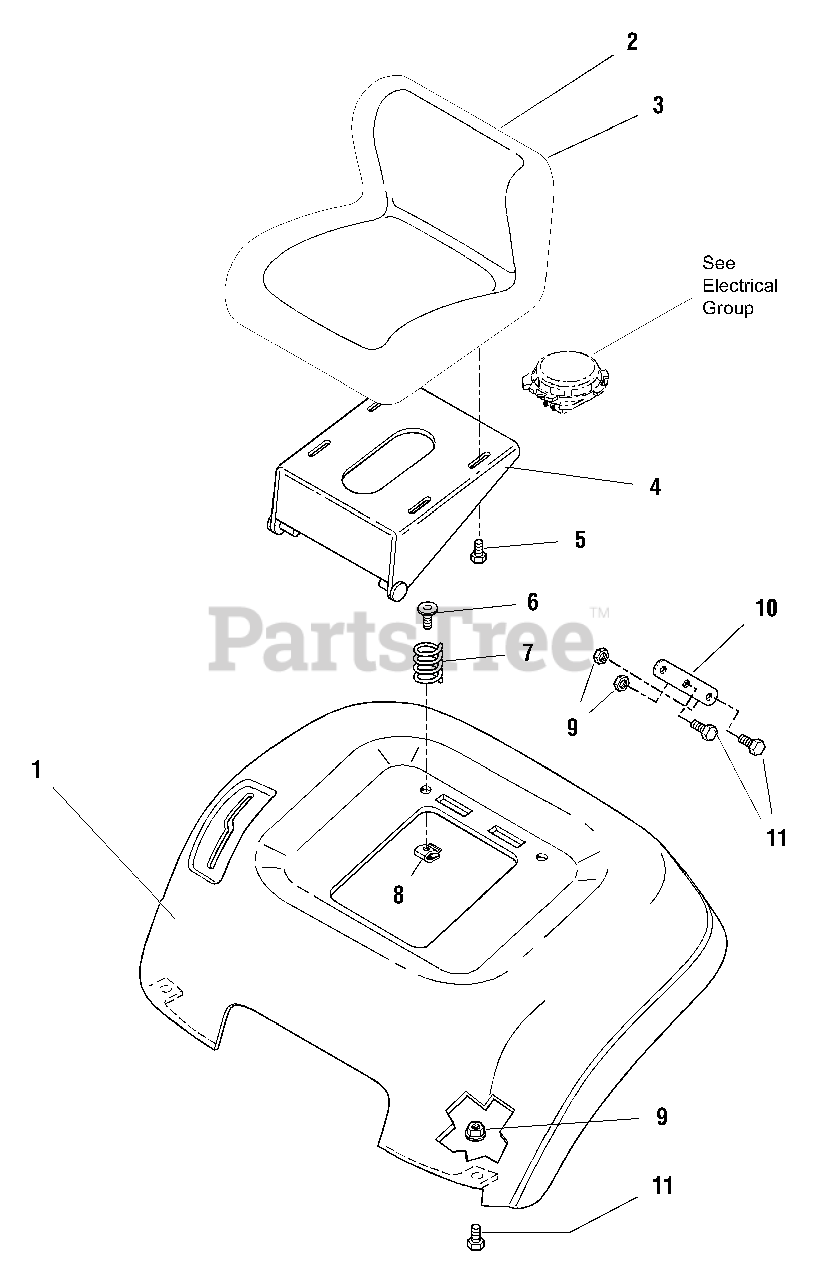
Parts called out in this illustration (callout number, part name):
1	SEAT DECK, (Cardinal Red)
2	SEAT, Black
3	SEAT, Cover
4	SUPPORT & PINS ASSEMBLY
5	CAPSCREW, Whiz Lock Hex Hd, 5/16-18 x 1/2
6	CAPSCREW, Flat Hd, Hex Socket, 5/16 - 18 x 1-1/4
8	SPEED NUT, Tinnerman Lug Type, 5/16-18
9	NUT, Hex Flange Whiz-Lock, 5/16-18
10	BAR, Seat Pivot
11	CAPSCREW, Whiz Lock Hex Hd, 5/16-18 x 3/4
